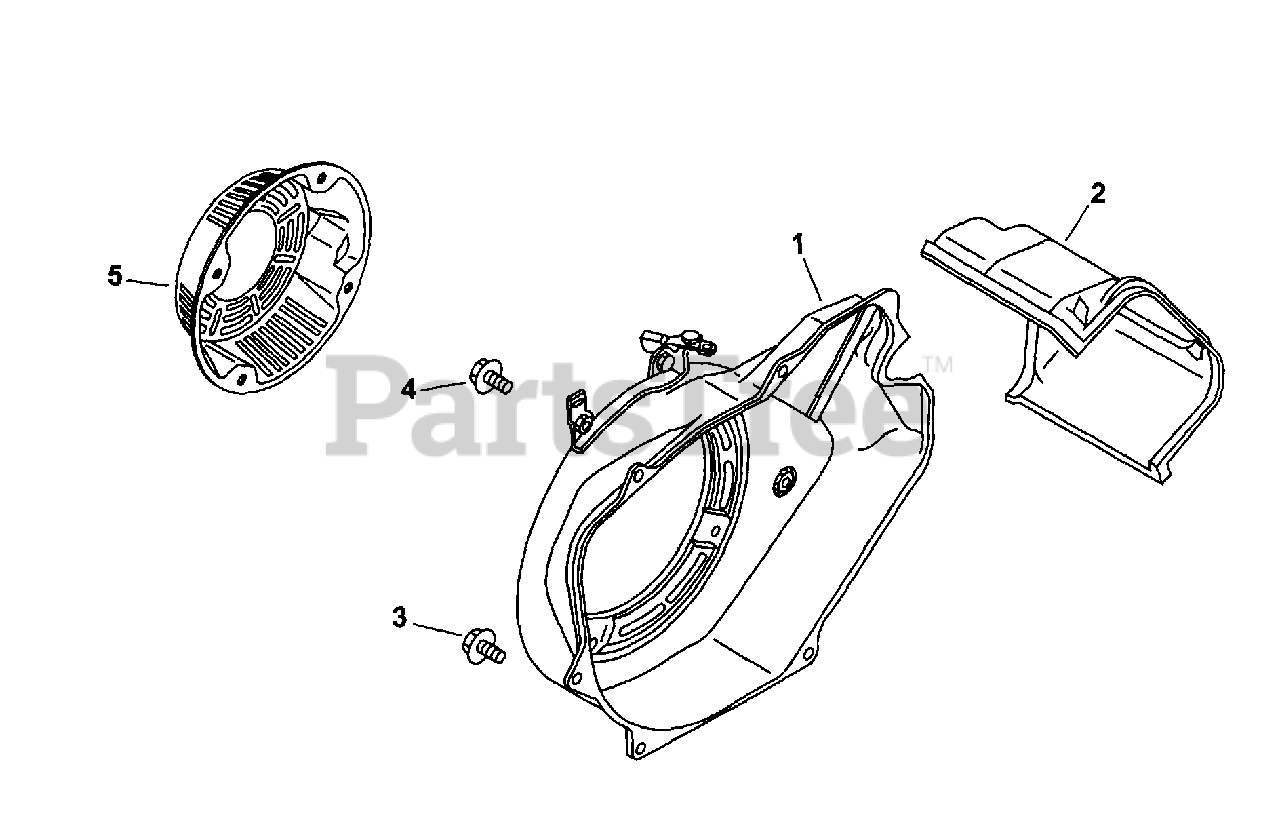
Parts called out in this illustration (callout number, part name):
1	KIT, BLOWER HOUSING
2	BAFFLE, CYL
4	SCREW, BH
